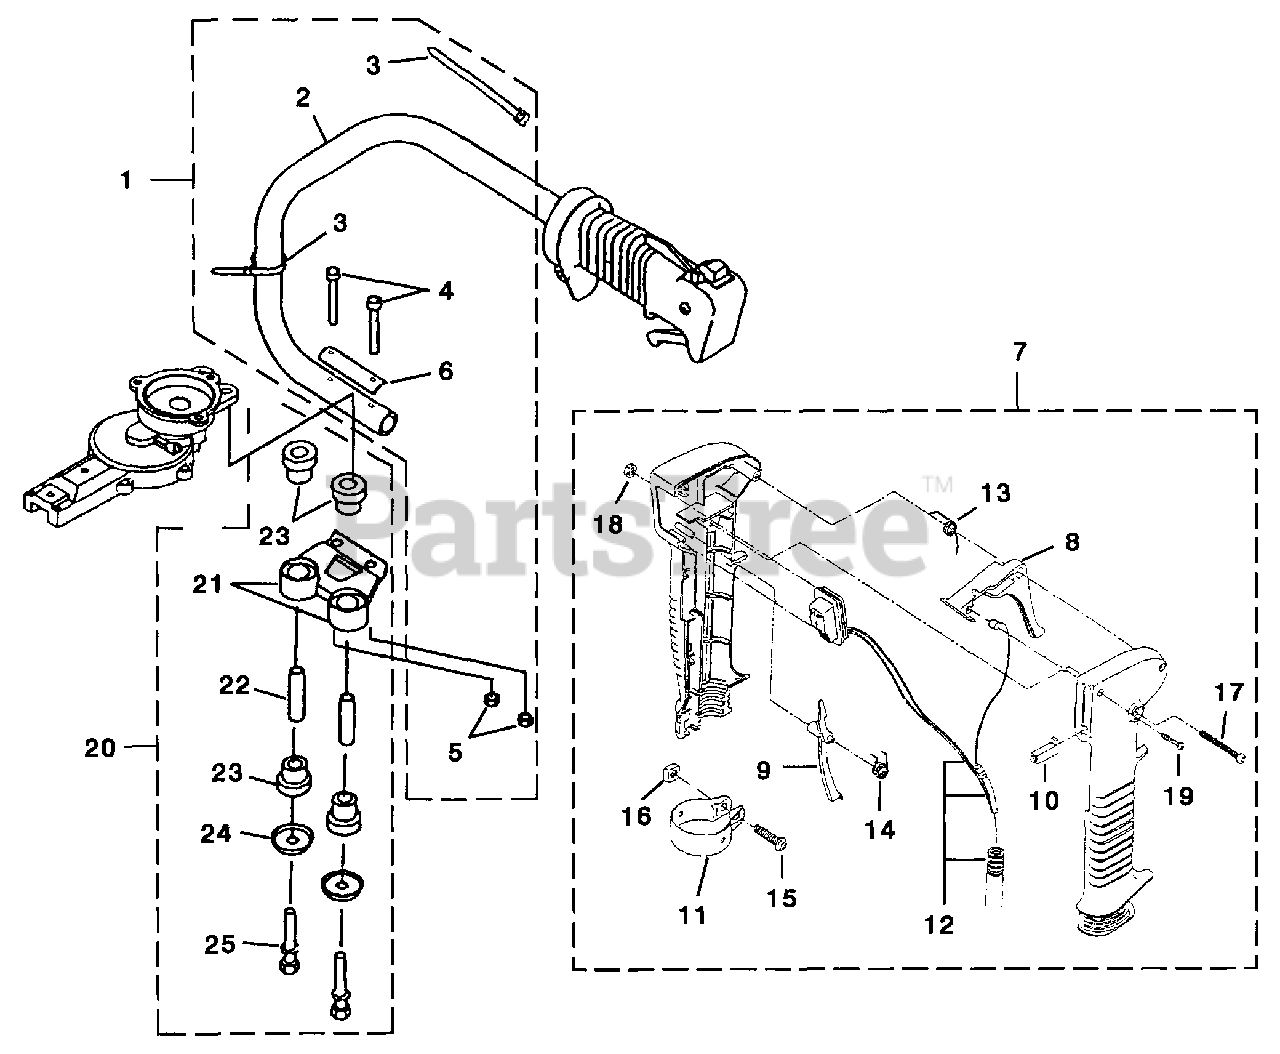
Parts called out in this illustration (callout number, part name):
1	REAR HANDLE BAR
2	HANDLE BAR-Left
3	TIE STRAPS-Grip
4	SCREW (M5 x 30)
5	NUT (M5)
6	PLATE-Handle Mounting
7	REAR HANDLE GRIP
8	TRIGGER-Throttle
9	LATCH-Throttle
10	LOCK-Throttle Start
12	THROTTLE CABLE W/ Harness
13	SPRING-Throttle Trigger
14	SPRING-Throttle Latch
19	SCREW-Self Tapping
20	ANTI VIBE KIT
21	BRACKET-Handle
22	SPACER-Collar
23	BUSHING-Anti Vibration
25	SCREW (M6 x 35 W SW)
